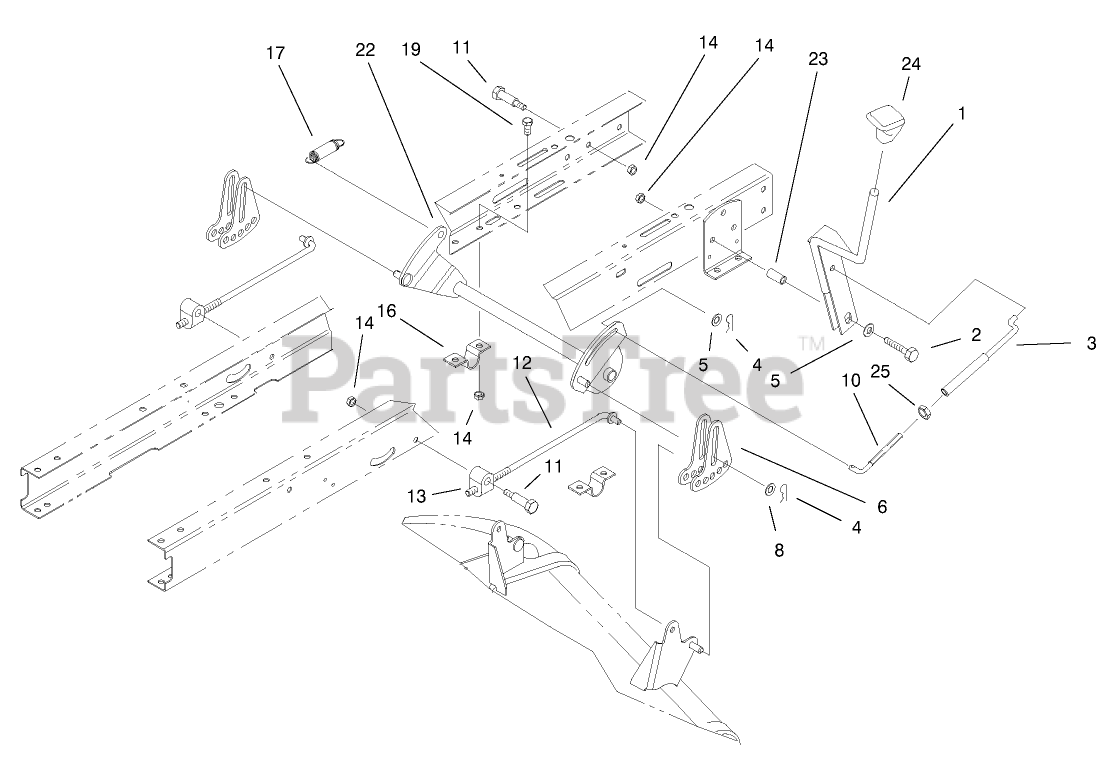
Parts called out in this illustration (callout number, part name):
2	SCREW-HH
3	HOC LINKAGE (WELDMENT)
5	WASHER-FLAT
6	LINK-ADJUSTING, HOC
8	WASHER-HARDENED
10	LINKAGE-HOC
11	SCREW-SHOULDER, HH
12	ROD-HANGER, REAR
13	TRUNNION-HOC
14	NUT-LOCK, NI
16	CLAMP-PIVOT, HOC
17	SPRING-EXTENSION
19	SCREW-HH
22	HOC PIVOT ASM (BLACK)
23	SPACER
24	KNOB-SHIFT
25	NUT-JAM
